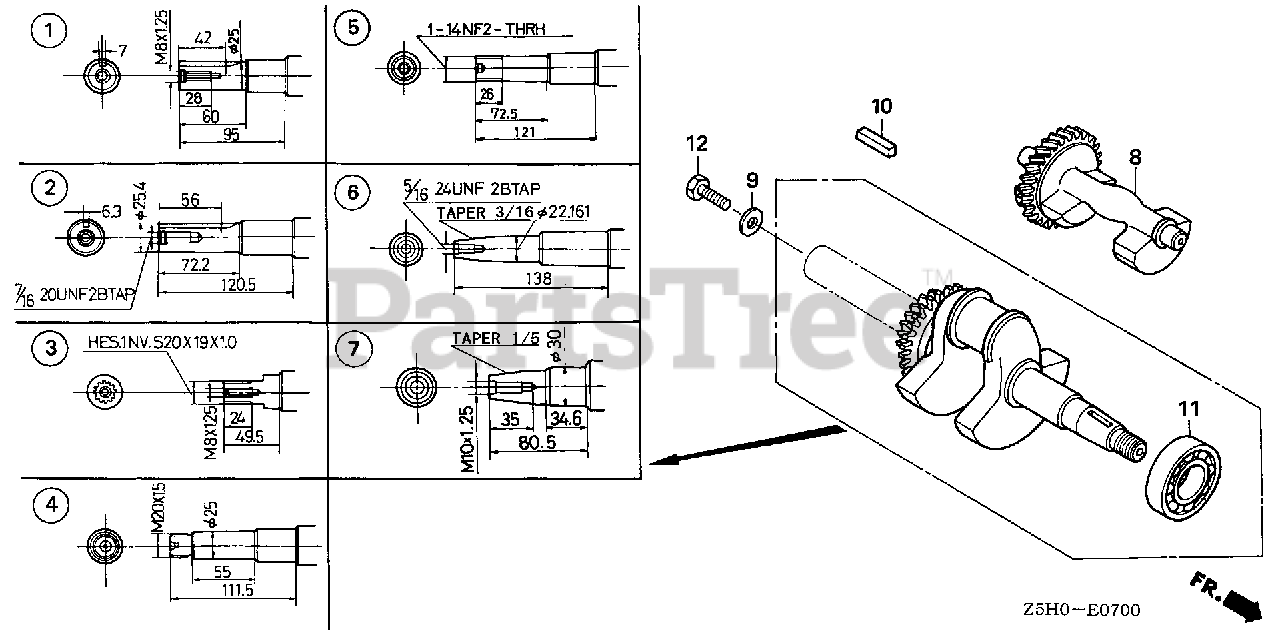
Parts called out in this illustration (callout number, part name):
2	CRANKSHAFT
8	WEIGHT, BALANCER
10	KEY (6.3X6.3X43)
11	BEARING, RADIAL BALL (6206 SH)
